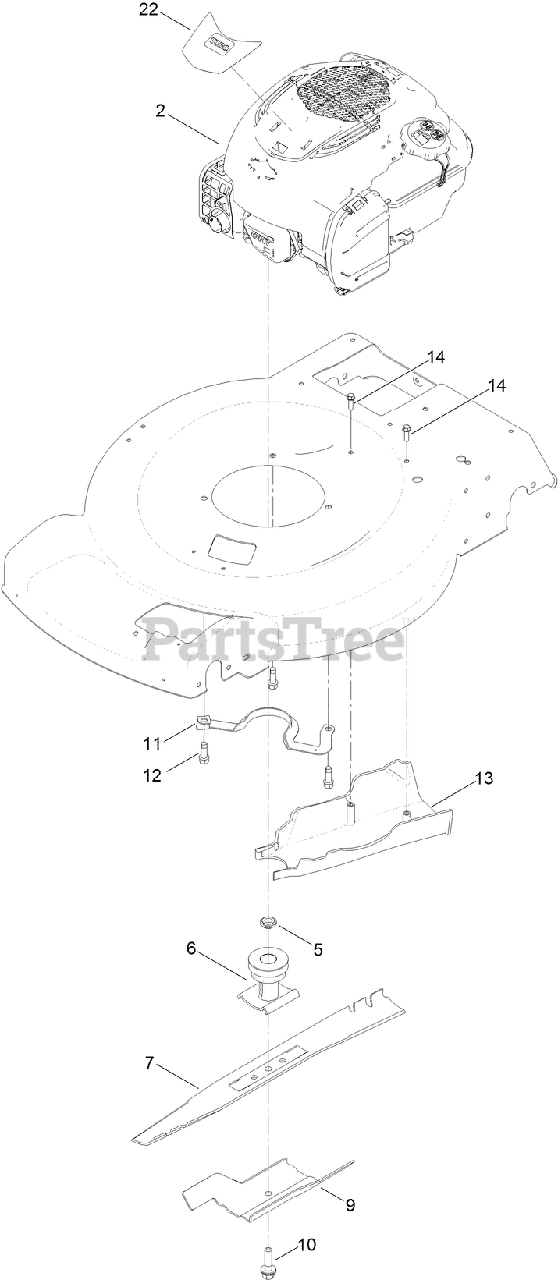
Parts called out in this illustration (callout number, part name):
5	SPACER-DRIVER
6	DRIVER-BLADE
9	ACCELERATOR-BLADE
10	BOLT-BLADE
11	GUIDE-BELT
12	SCREW-TAPTITE
13	COVER-BELT, REAR
14	SCREW-HWH
22	DECAL-SHROUD
